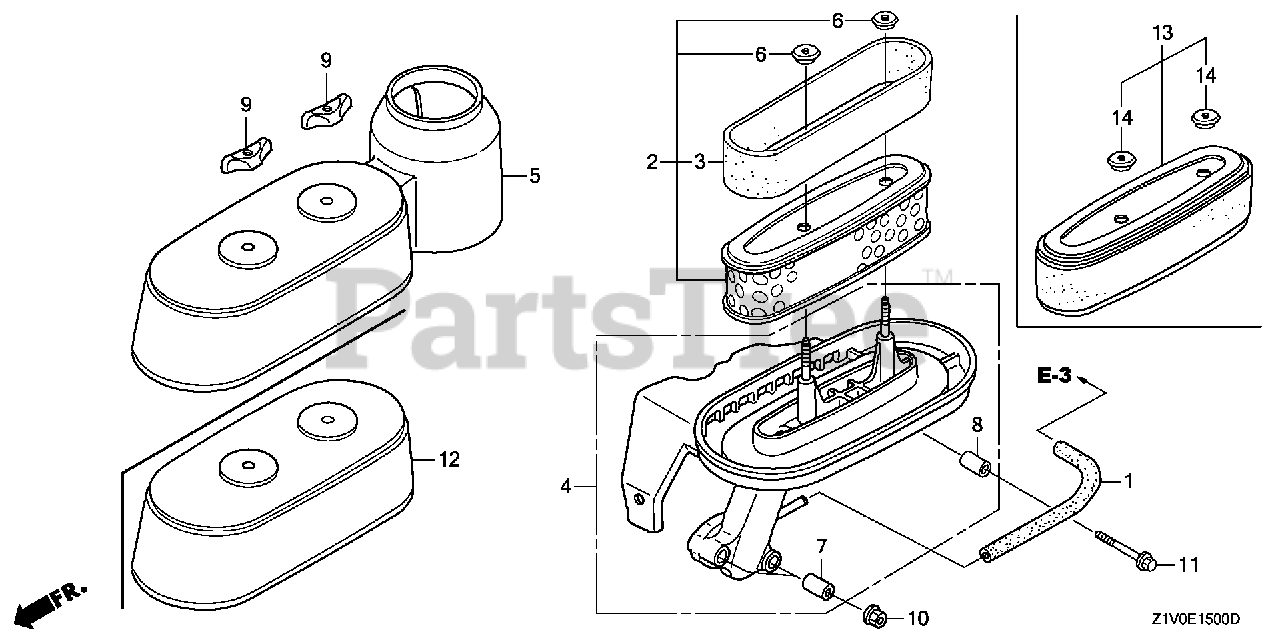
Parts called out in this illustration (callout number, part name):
1	TUBE, BREATHER
2	ELEMENT, AIR CLEANER
3	FILTER (OUTER)
4	HOUSING, AIR CLEANER
5	COVER, AIR CLEANER
6	GROMMET, AIR CLEANER
7	COLLAR, AIR CLEANER
8	COLLAR B, AIR CLEANER
9	NUT, AIR CLEANER
10	NUT, FLANGE (6MM)
11	BOLT, FLANGE (6X35)
